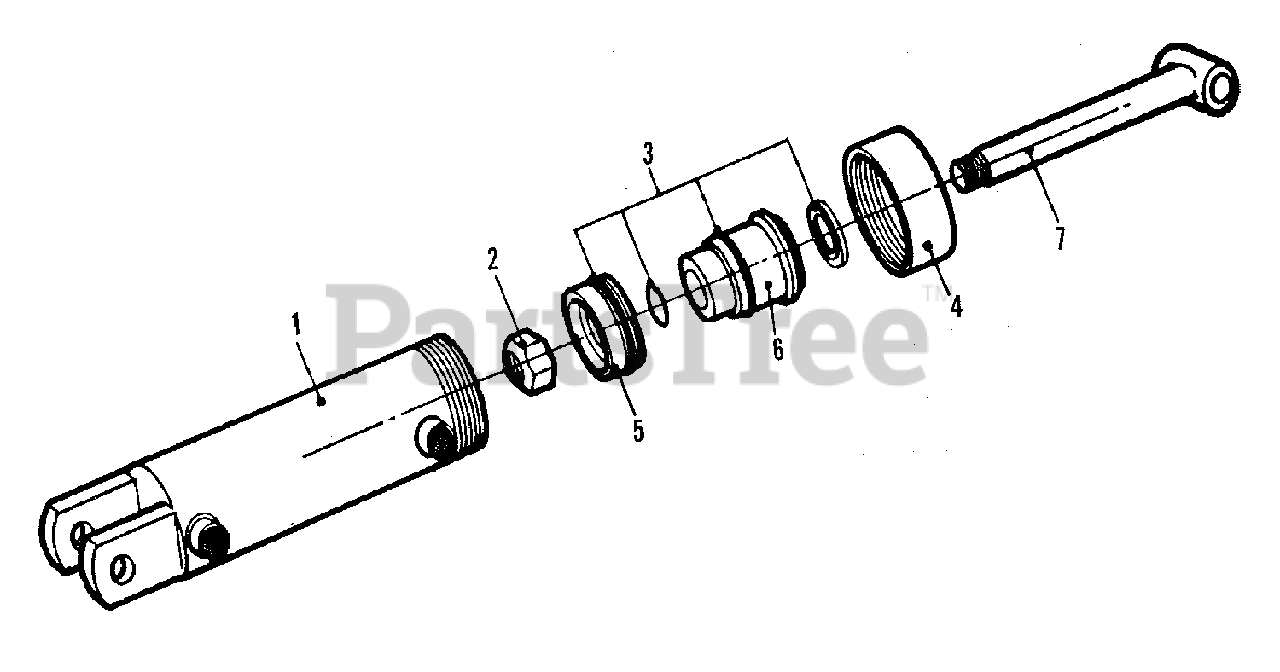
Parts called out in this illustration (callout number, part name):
1	CASING, Cylinder
2	NUT, Piston
3	SEAL KIT, Hydraulic Lift Cylinder
5	PISTON (w/SEAL KIT)
6	GLAND (w/SEAL KIT)
7	ROD, Lift Cylinder
